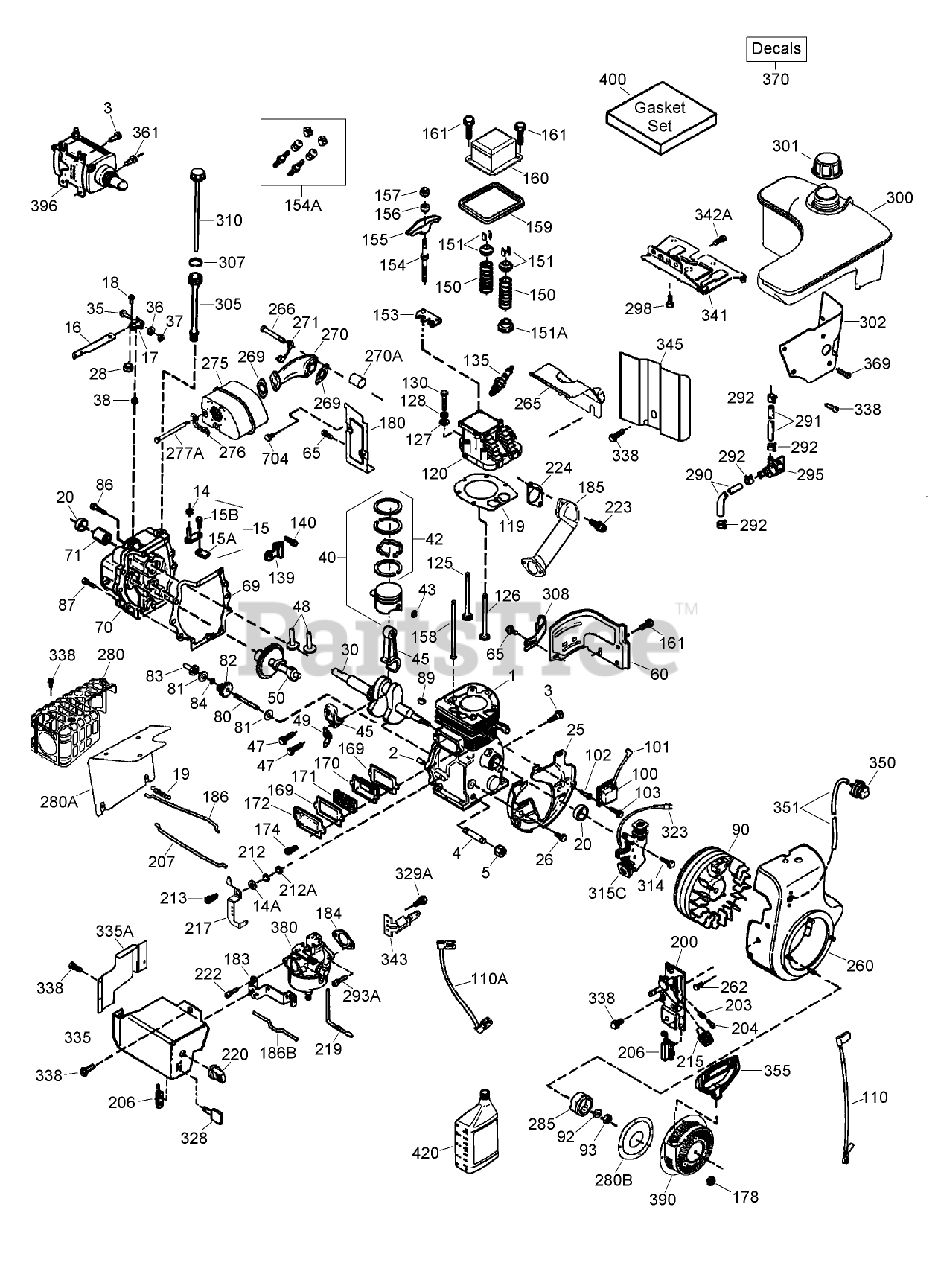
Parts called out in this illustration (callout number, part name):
178	Nut and Lock Washer (1/4-28)
180	Extension-Housing, Blower
183	Bracket-Choke
184	Gasket-Carburetor To Intake Pipe
185	Pipe-Intake
186	Link-Governor
186B	Spring-Choke
200	Bracket-Control (Incl. Ref. #203, 204 and 206)
203	Spring-Compression
204	Screw (T-10, 5-40x7/16)
206	Terminal
207	55106 TWO WHEEL TRA
212	Bushing
212A	Washer
213	Screw (10-24 X 29/32)
215	Knob-Control
217	Lever-Bellcrank
219	Rod-Choke
220	Knob-Control
222	Screw (10-32 X 15/32)
223	Screw (T-30, 5/16-18 X 7/8)
224	Gasket-Pipe
260	Housing-Blower
262	Screw (5/16-18x9/16)
265	Cover-Head, Cylinder
266	Screw (5/16-18 X 1-9/32)
269	Gasket-Manifold, Exhaust
270	55107 SNWTHWR ATTCH
270A	Liner-Port, Exhaust
271	Plate-Locking
275	Muffler
276	Plate-Locking
277A	Screw (5/16-18 X 4-1/2)
280	Cylinder (Incl. 2, 20 150)
280A	Shield-Heat, Radiation
280B	Baffle-Restrictor, Air
285	Cup-Starter
290	Line-Fuel, Low Permeation (32.0 Length)
291	Line-Fuel, Low Permeation (8.62)
292	Clamp-Line, Fuel
293A	Screw (T-30, 1/4-20 X 27-32)
295	Valve-Shut Off, Fuel
298	Screw (1/4-15x7/8)
300	Tank-Fuel (Includs 292, 301)
301	Cap-Fuel (Black) (1-1/2 I D)
302	Extension-Tank, Fuel
305	Tube-Fill, Oil
307	O-Ring
308	Clip-Tube, Fill
310	Dipstick
314	Screw (1/4-20 x 3/4)
315C	Coil-Alternator, 18 Watt (Includes 323)
323	Terminal
328	Key-Ignition
329A	Screw (8-32 x 23/64)
335	Cover-Carburetor (Front)
335A	Cover-Carburetor
338	Screw (10-32 x 1/2)
341	Bracket-Tank, Fuel
342A	Screw (5/16-18 X 7/8)
343	Bracket-Switch, Key
345	Baffle-Heat
350	Primer ASM
351	Line-Primer
355	Handle-Starter, Mitten Grip
361	Screw (T-30, 1/4-20x15/32)
369	Screw (12-16 x 5/8)
370	Decal-Primer, International Symbol
370	Instruction Decal-Caution, read owner manual
370	Decal-Tecumseh Logo for Top of Recoil Starter
370	Decal-Choke
370	Decal-Start Button, Electric
370	Decal-Hot Surfaces
380	Carburetor (Incl. Ref.# 184)
390	Starter-Rewind
396	Electric Starter Motor ASM (220 Volt)
400	Gasket Set
420	Oil-Engine, S A E 5W30
704	Screw (1/4-20 X 5/8)
999	Winter Maintenance Kit (S A E 5W30 Oil)
